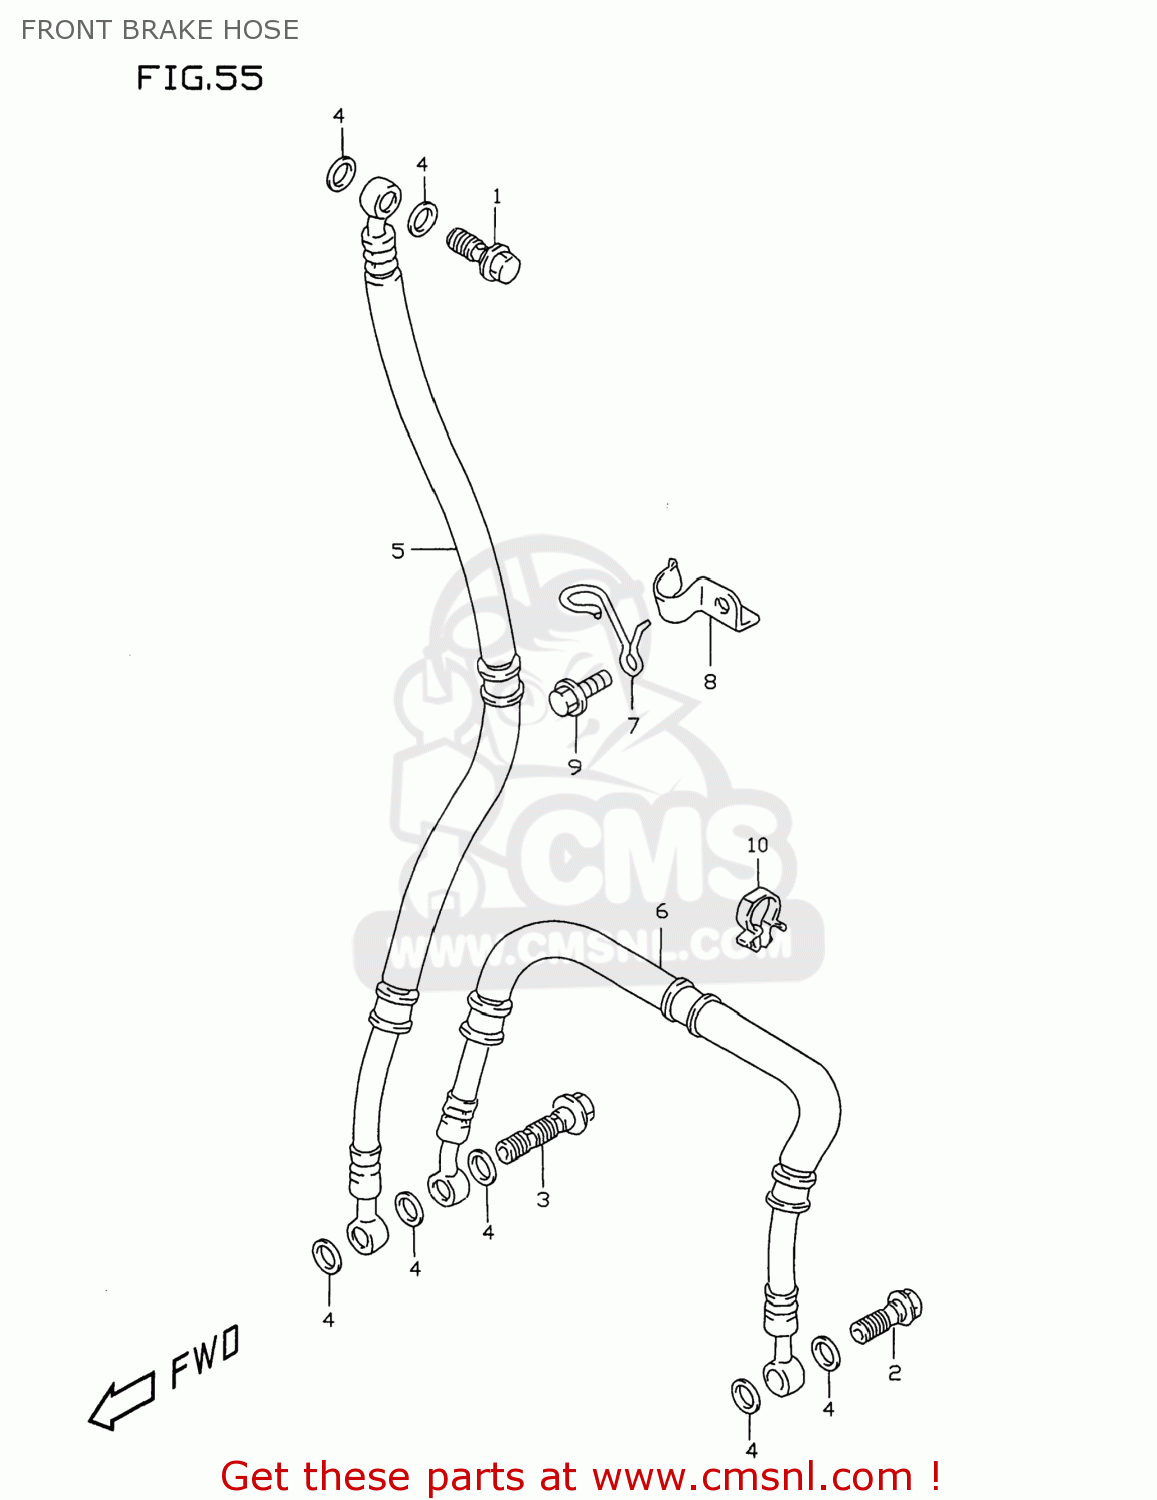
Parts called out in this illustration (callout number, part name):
1	BOLT UNION
2	BOLT UNION
3	BOLT UNION
4	WASHER(10X15X1.5)
5	HOSE,FR BRAKE NO.1
6	HOSE,FR BRAKE NO.2
7	GUIDE,FRONT BRAKE HOSE
8	CLAMP,FR BRAKE HOSE UPR
9	BOLT
10	CLAMP
